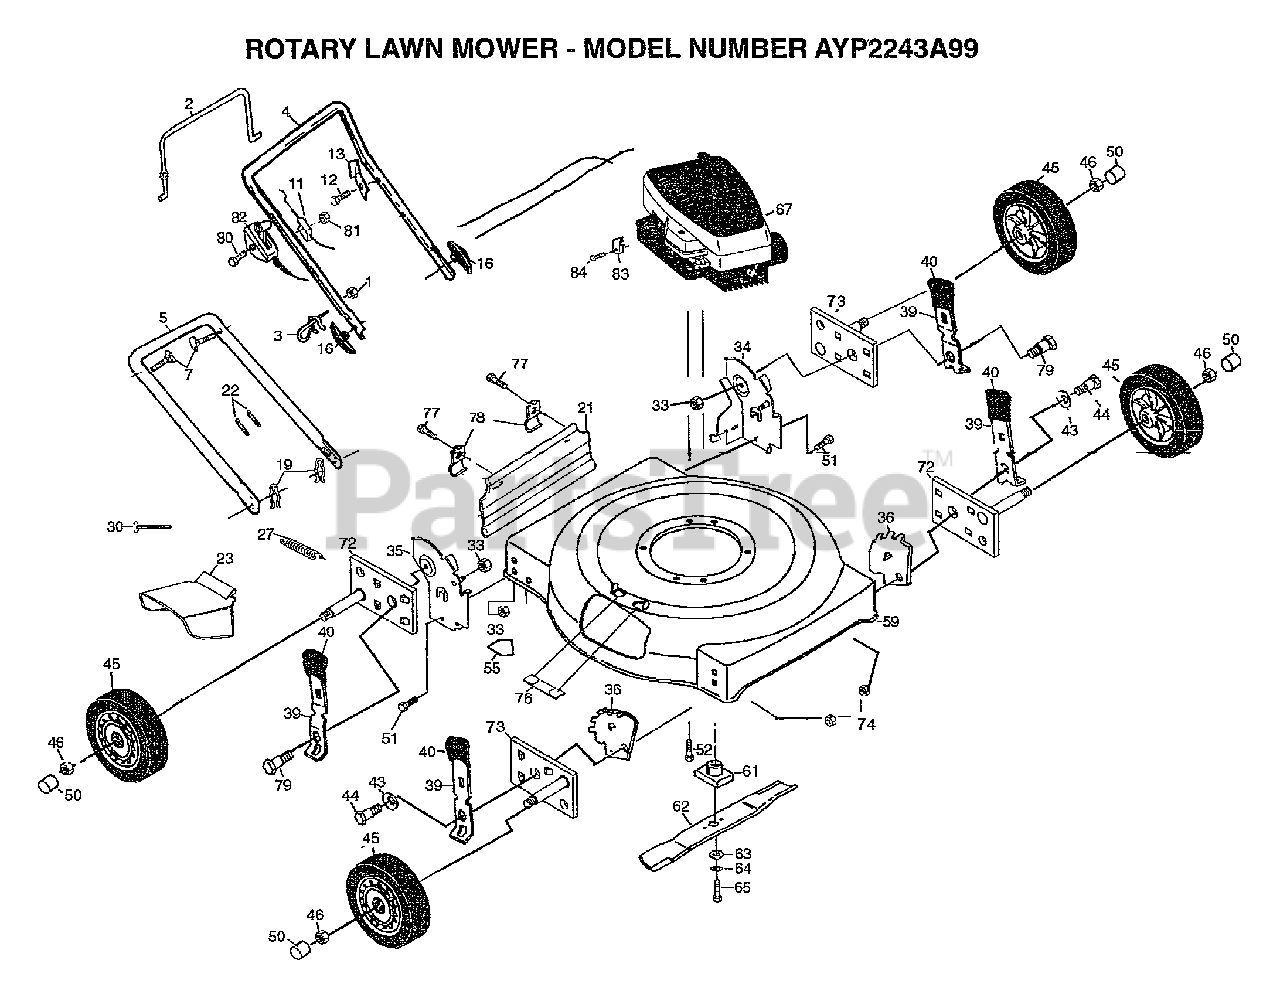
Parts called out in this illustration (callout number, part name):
2	CONTROL BAR PM
3	ROPE GUIDE
5	LOWER HANDLE
7	BOLT.HANDLE.LM
11	"CABLE.MZR.47"""
12	TAPPING SCREW
13	"BRKT,UPSTOP"
16	"NUT,WING PM"
19	HAIRPIN COTTER
21	"SKIRT.REAR.22SD/ECON.21"""
23	GUARD.DISCHARGE
27	HINGE.SPRING
30	HINGE.ROD.22SD
33	LOCKNUT
34	WHL BRKT SUPT LEFT
35	WHL BRKT SUPT RIGHT
36	WHEEL.BRKT.ADJ.
39	SLECTOR SPRING
40	KNOB PM
43	WASHER.BELLEVELLE
44	SHOULDER BOLT
45	WHEEL.ASM
46	HEX FLANGE LOCKNT
50	HUB CAP-PLASTIC
51	SCREW 1/4X20
52	BOLT.ENG.3/8-16
55	DECAL-DANGER PM
59	KIT.HSG.22SD.PUSH.RED
61	ADAPTOR.BLADE.LM
62	"BLADE.MULCH.22"""
63	"WASHER,HARDEN"
64	LOCKWASHER
65	SCREW
72	ARM.ASM.AXLE.RR/LF.
73	ARM.ASM.AXLE.LR/RF
74	LOCKNUT
76	CLIP.CLOSECUT.22SD
77	TAPPING SCREW
78	"BRKT,DEFL PM"
79	SHOULDER BOLT
80	SCREW.HXHD.WASH.
82	"CONTROL, THROTTLE"
83	CABLE CLAMP
84	SCREW PM
